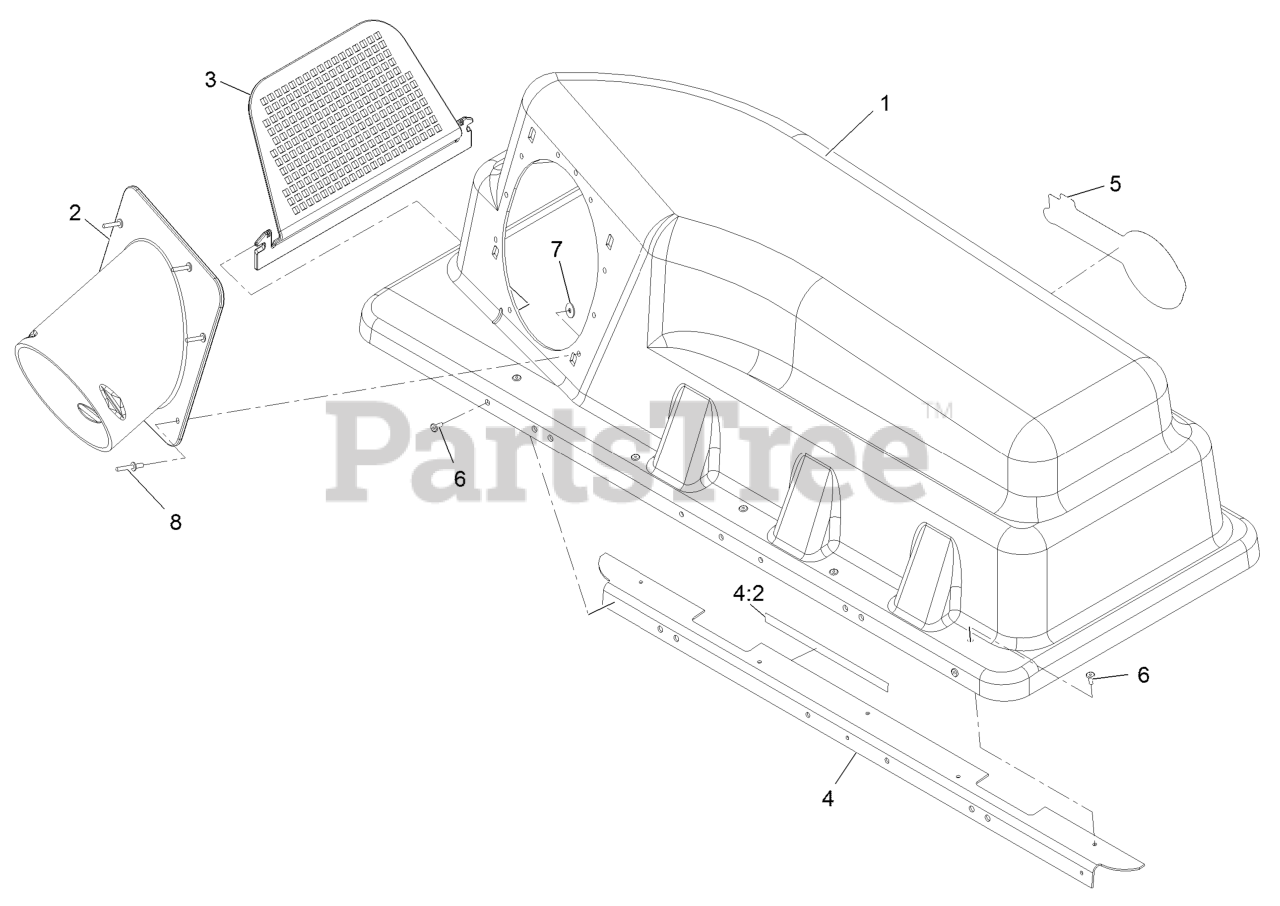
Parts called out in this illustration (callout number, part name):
1	HOOD,BAGGER
2	TUBE,UPPER
3	SCREEN-BAGGER
4	ASM,STIFFENER W/DECAL
4:2	DECAL-CAUTION, BAGGER
5	DECAL, EXMARK LOGO
6	RIVET-BLIND
7	WASHER-FLAT
8	RIVET-POP
